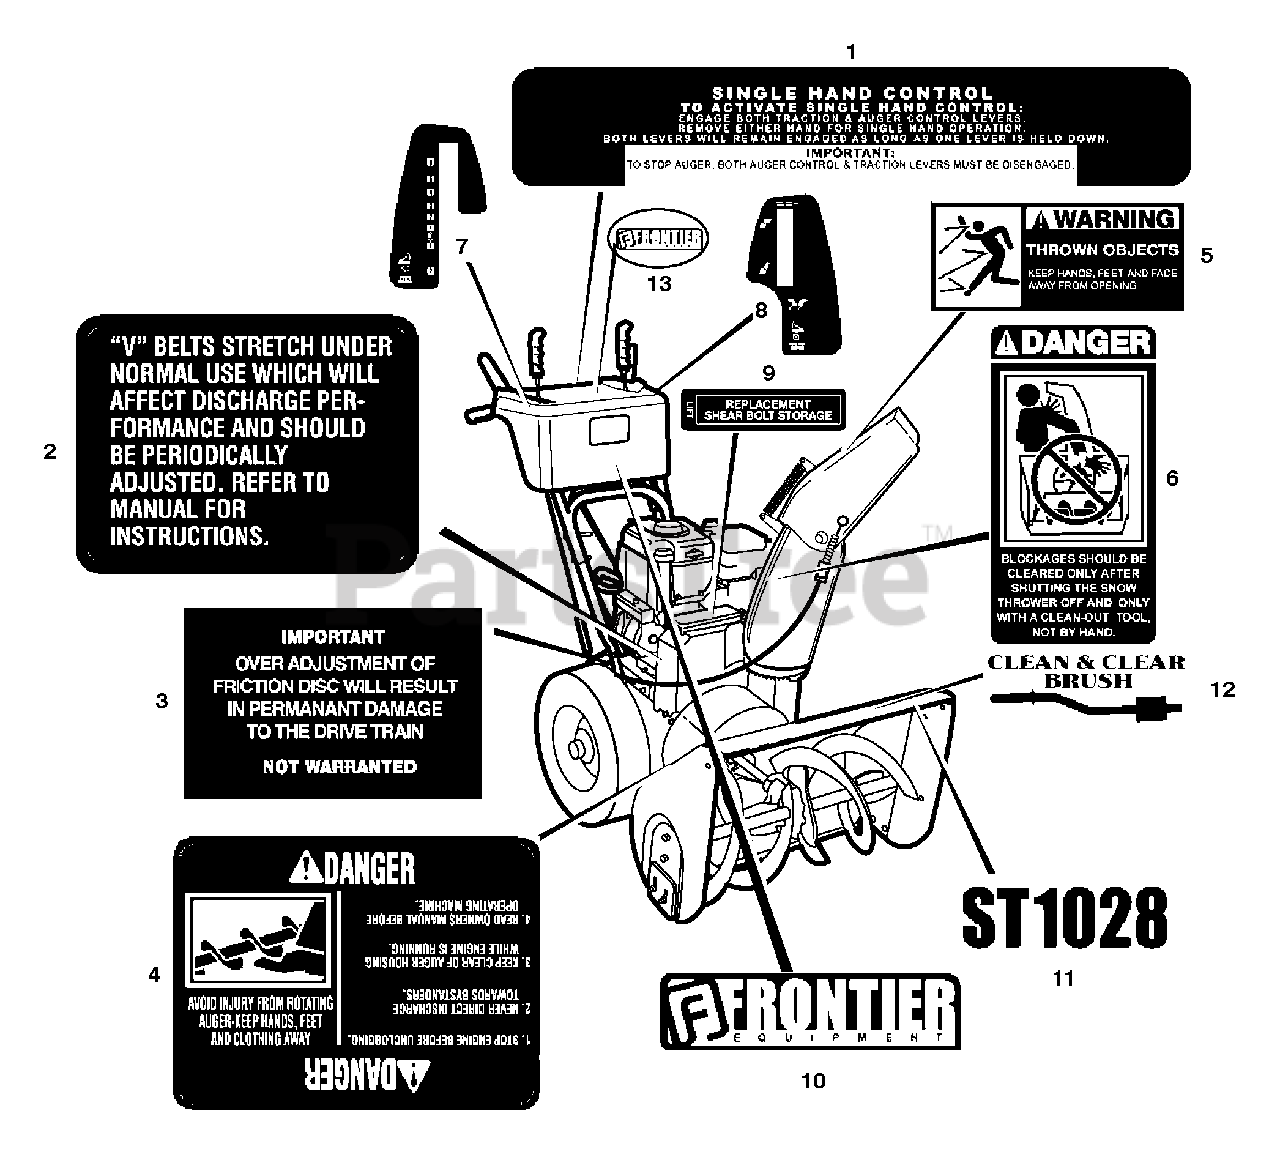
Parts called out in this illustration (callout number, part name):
1	DECAL, SINGLE HAND CONTROL
2	DECAL, V-BELTS
3	DECAL, OVER ADJUSTMENT
4	DECAL, ROTATING AUGER
5	DECAL, DANGER
6	DECAL, UNCLOGGING CHUTE
7	DECAL, SPEED CONTROL
8	DECAL, REMOTE CHUTE CONTROL
9	DECAL, SHEAR BOLTS
10	LOGO NAMEPLATE, FRONTIER
11	DECAL, ST1028
12	DECAL, CLEAN & CLEAR BRUSH
13	DECAL, PANEL
